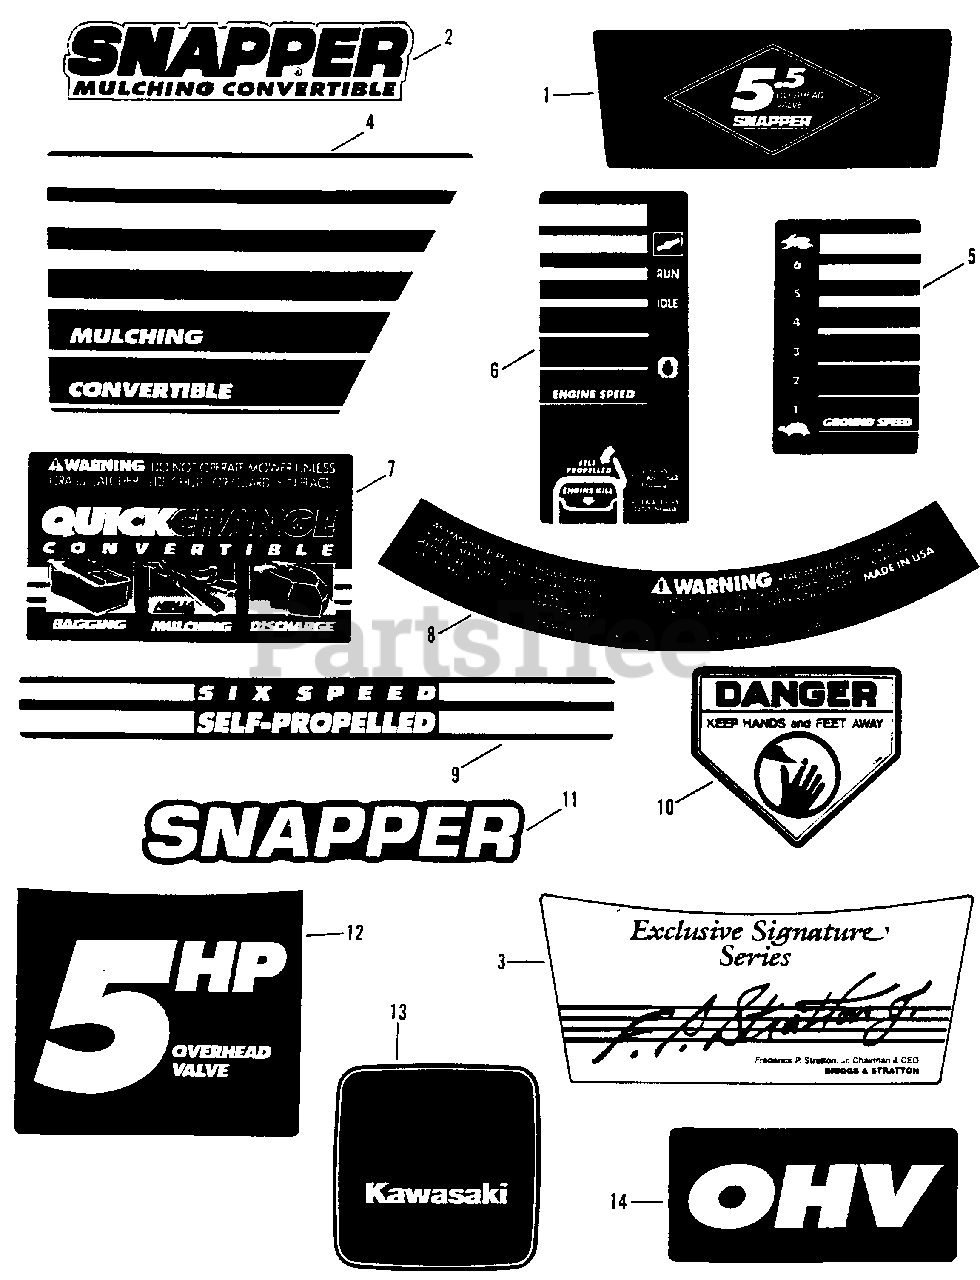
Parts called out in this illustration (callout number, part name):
1	DECAL, Briggs 5.5 Overhead Valve
2	DECAL - SNAPPER, Nameplate
3	DECAL, Signature
4	DECAL, Mulching Convertible
5	DECAL, Ground Speed
6	DECAL, Engine Speed (Briggs Engine)
7	DECAL, Quick Change Convertible
8	DECAL, WARNING
9	DECAL, Six Speed Self Propelled
10	DECAL, DANGER
11	DECAL, SNAPPER, Molded Logo (Chrome)
12	DECAL, Engine 5 HP
13	DECAL, Kawasaki Engine Start
14	DECAL, OHV
